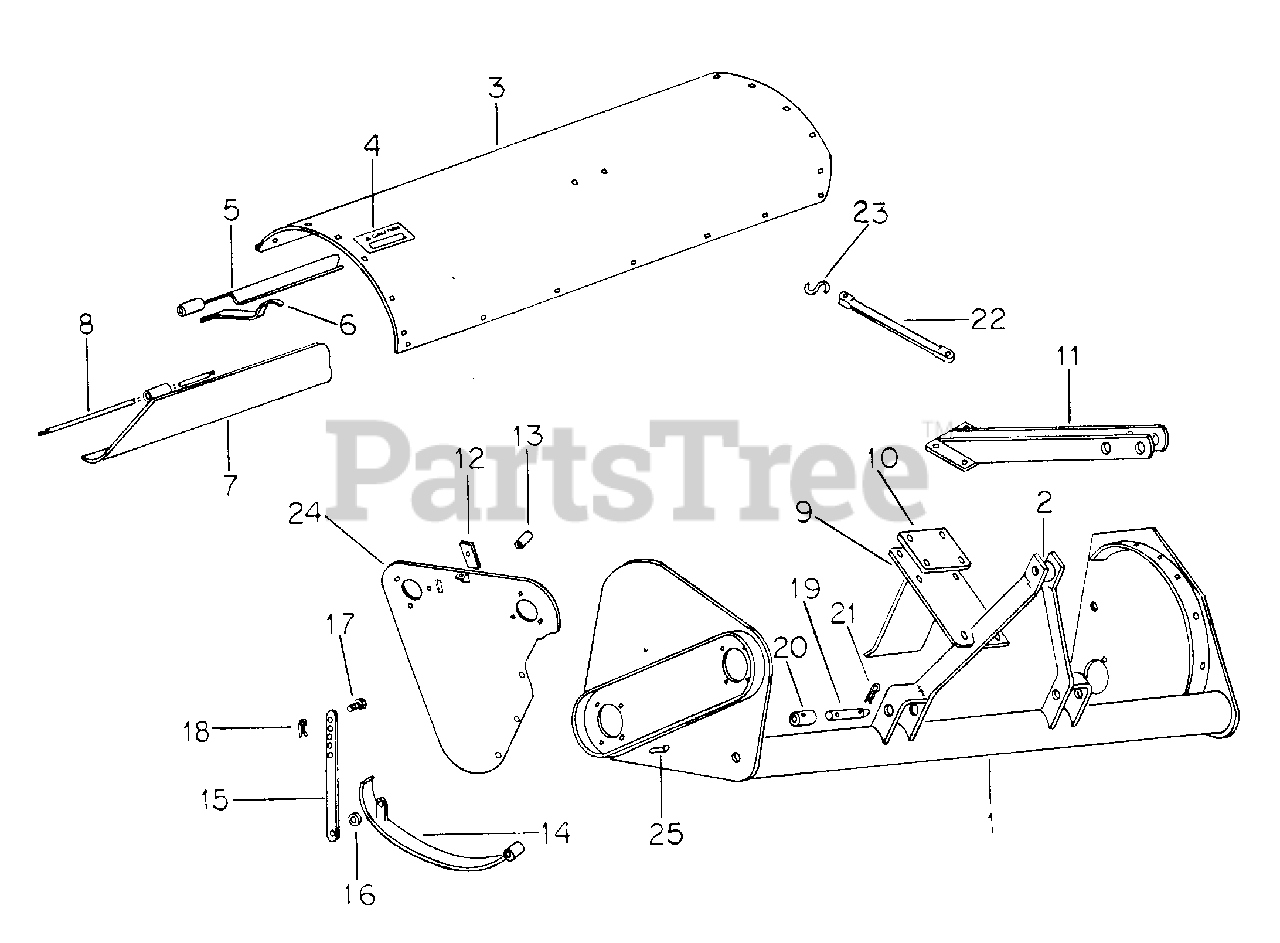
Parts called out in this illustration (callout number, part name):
1	FRAME
2	SPACER, 1/2 x 1.125 X/STRG PIPE
3	SHROUD
4	PRODUCT GRAPHIC, CAUTION
5	BRACKET, HINGE
6	SUPPORT
7	BLADE, LEVEL
8	ROD, HINGE
9	SUPPORT, MOUNT
10	SPACER
11	LINK
12	BAR, IDLER SUPPORT - STRAP
13	SPACER 1/2 x 2 FRAME SUPPORT
14	SHOE
15	BAR, ADJUST
17	BOLT SPECIAL
18	PIN, QA
20	SPACER, PIN
21	PIN, QA
22	STRAP, TIE
23	S-HOOK
24	COVER, INNER
25	BOLT, SPECIAL CARRIAGE
113961	SCREW 1/4 x 1-1/4 PLN R/HDS MACH
